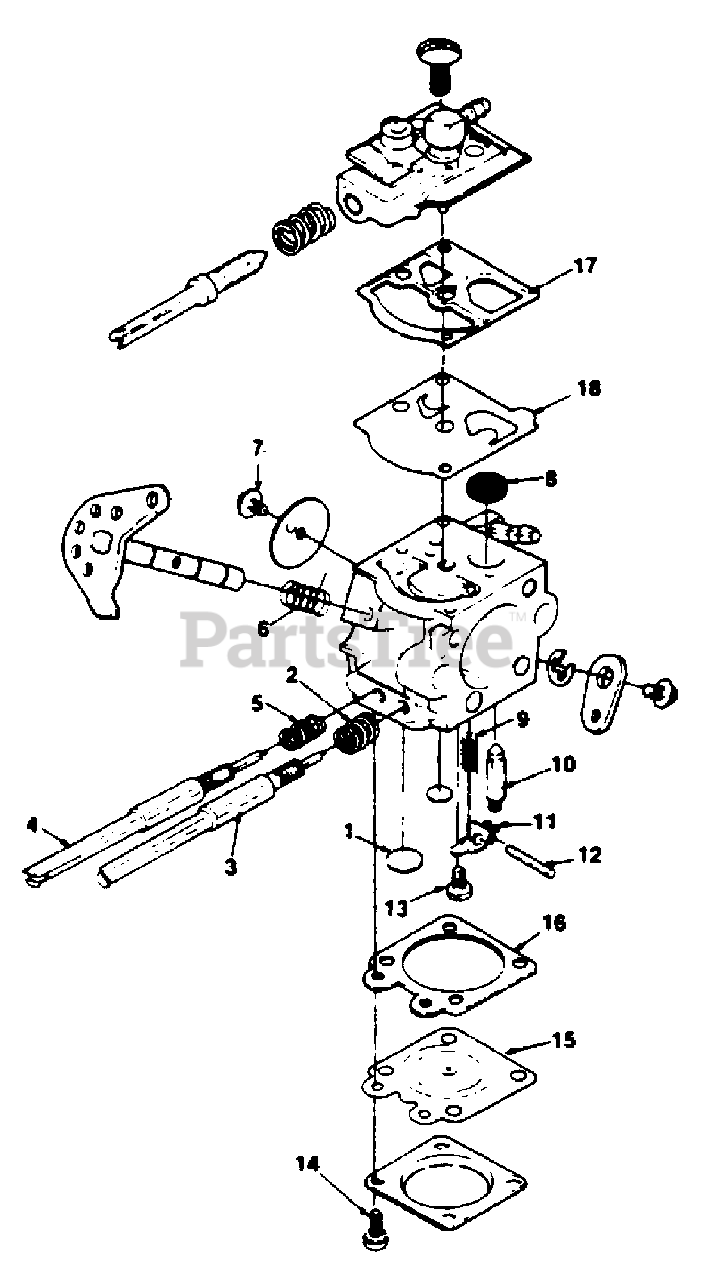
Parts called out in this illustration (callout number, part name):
1	Repair Kit
2	Repair Kit
3	Repair Kit
4	Repair Kit
5	Repair Kit
6	Repair Kit
7	Repair Kit
8	Repair Kit
9	Repair Kit
10	Repair Kit
11	Repair Kit
12	Repair Kit
13	Repair Kit
14	Repair Kit
15	Repair Kit
16	Repair Kit
17	Repair Kit
18	Repair Kit
